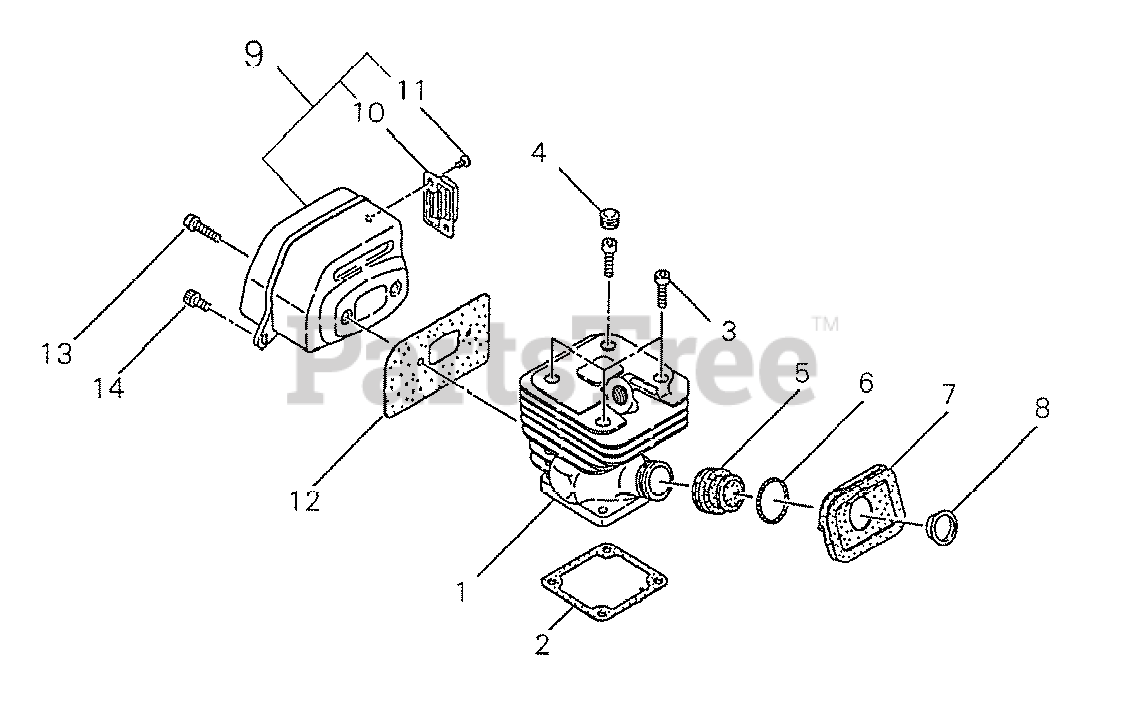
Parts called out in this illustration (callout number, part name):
1	CYLINDER
2	GASKET, CYLINDER
3	SCREW - 5X18
4	PLUG
5	BOOT
6	SPRING
7	SEAL
8	SLEEVE
9	MUFFLER KIT
10	GUIDE, EXHAUST
11	SCREW - 4X8
12	SHIELD, EXHAUST
13	SCREW - 5X18
14	SCREW - 5X12
